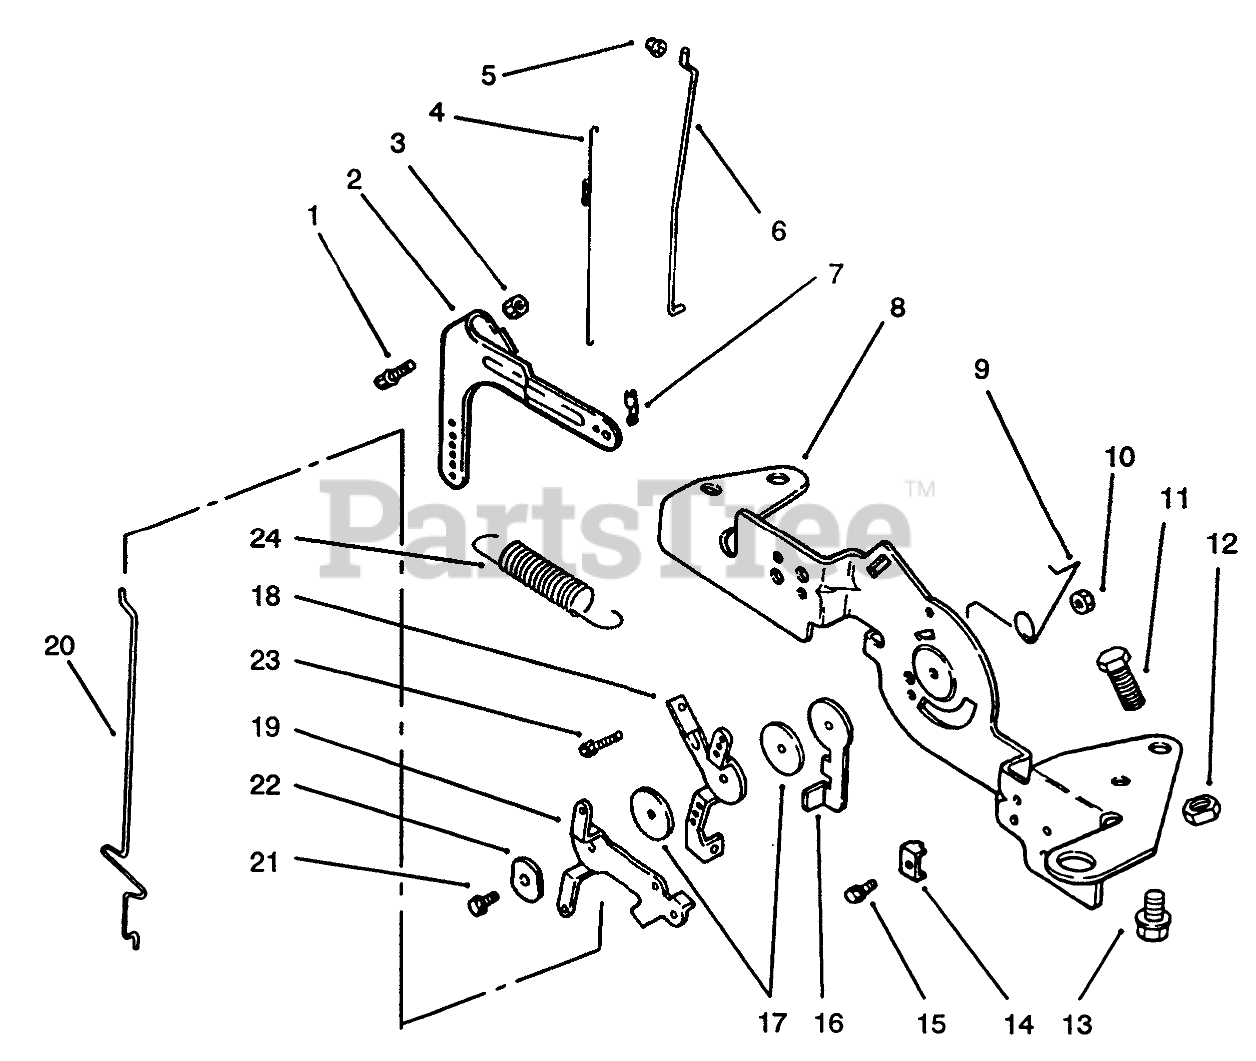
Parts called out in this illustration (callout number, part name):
1	Screw M6x1.0x25 (Only On: 72103, 72083)
2	Lever-Governor (Only On: 72103, 72083)
3	Nut M6x1.0 (Only On: 72103, 72083)
4	Spring-Linkage (Only On: 72103, 72083)
5	Bushing-Linkage (Only On: 72103, 72083)
6	Linkage-Throttle (Only On: 72103, 72083)
7	Bushing-Linkage (Only On: 72103, 72083)
8	Bracket-Control (Only On: 72103, 72083)
9	Spring-Choke Return (Only On: 72103, 72083)
10	Nut M5x0.8 (Only On: 72103, 72083)
11	Screw M5x0.8x16 (Only On: 72103, 72083)
12	Nut-Hex M4x0.7 (Only On: 72103, 72083)
13	Screw M6x1.0x16 (Only On: 72103, 72083)
14	Clamp-Cable (Only On: 72103, 72083)
15	Screw M5x0.8x16 (Only On: 72103, 72083)
16	Lever-Throttle Actuator (Only On: 72103, 72083)
17	Washer (Only On: 72103, 72083)
18	Lever-Throttle Control (Only On: 72103, 72083)
19	Lever-Choke (Only On: 72103, 72083)
20	Linkage-Choke (Only On: 72103, 72083)
21	Screw M5x0.8x20 (Only On: 72103, 72083)
22	Washer-Wave (Only On: 72103, 72083)
23	Screw M4x0.7x24 (Only On: 72103, 72083)
24	Spring-Governor (Only On: 72103, 72083)
